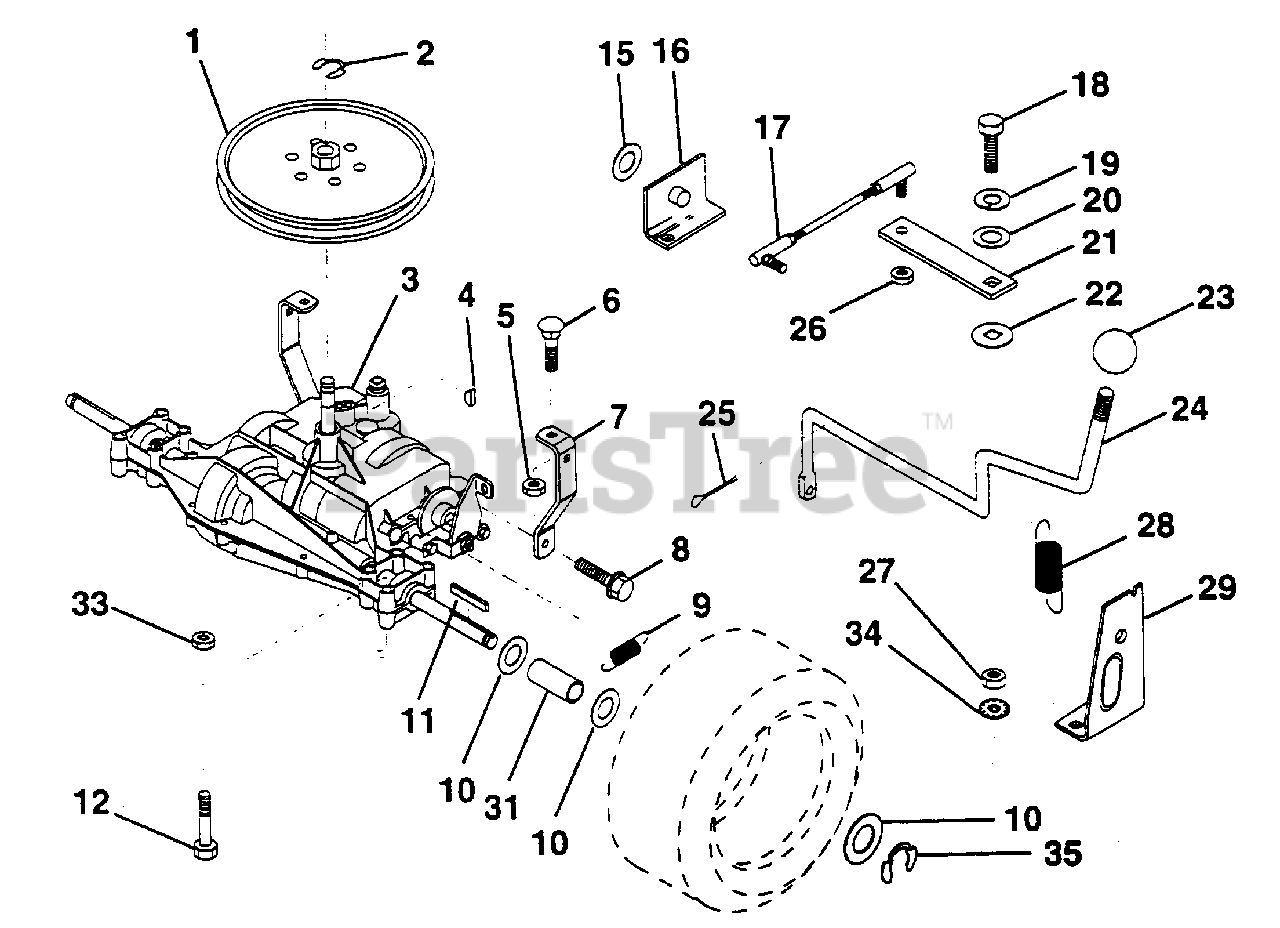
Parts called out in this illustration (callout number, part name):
2	Ring, Retainer
4	Key, Woodruff #9
5	Nut, Crownlock 5/16-18
6	Bolt, Carriage 5/16-18 UNC x 3/4
7	Strap, Torque
8	Screw 5/16 - 18 x 3/4
9	Spring, Brake
10	Washer 25/32 x 1-1/4 x 16 Ga.
12	Bolt, Fin Hex 5/16-18 x 2-1/2
15	Washer 17/32 x 1 x 16 Ga.
16	Support, Handle Shift L. H.
18	Bolt, Fin Hex 1/4-28 UNF x 3/4 Gr. 8
19	Washer, Lock 1/4
20	Washer 9/32 x 3/4 x 10 Ga.
22	Washer, Shift Plate
23	Knob, Shift Control
25	Pin, Cotter 1/8 x 1
26	Nut, Hex Nylon
27	Nut, Keps 5/16-18
28	Extension, Spring
29	Support, Handle Shift R. H.
31	Spacer, Split
33	Nut Crownlock 3/8 - 16
34	Washer External Tooth 5/16
